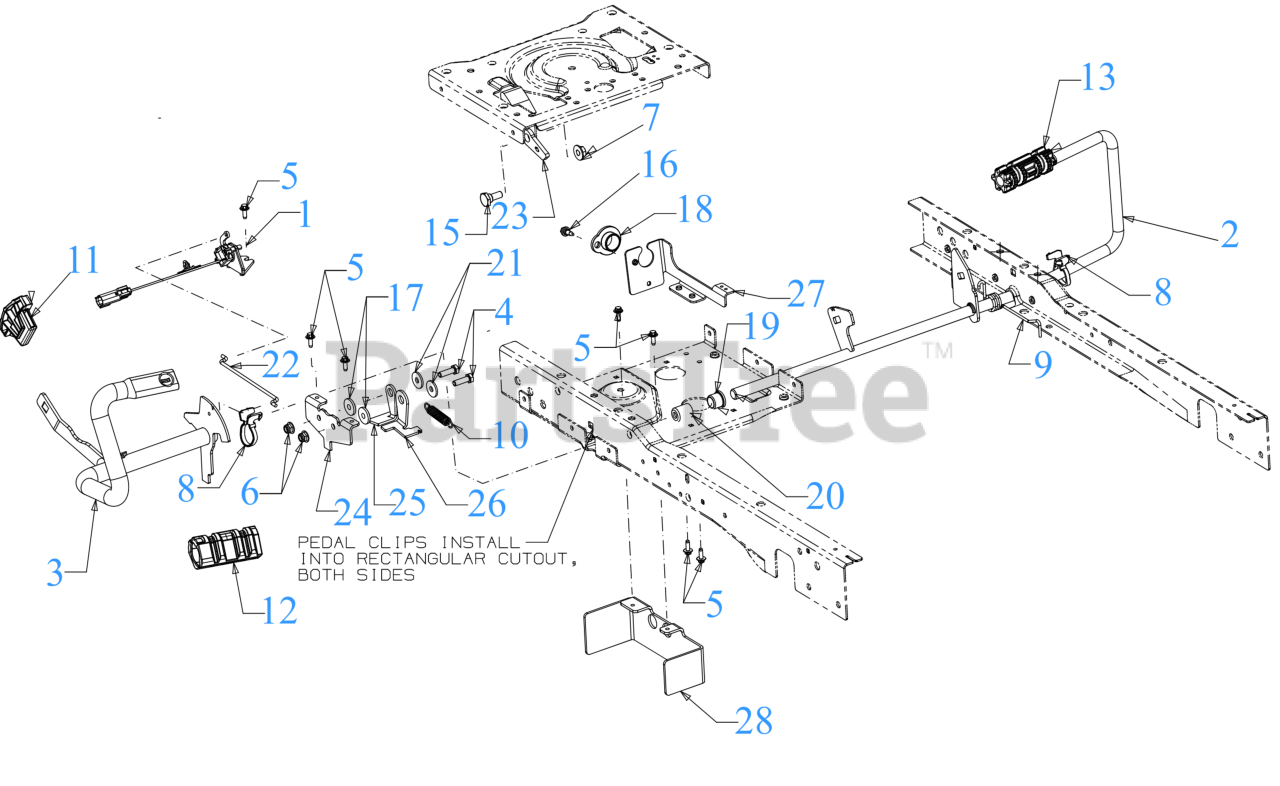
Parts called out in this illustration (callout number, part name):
1	THROTTLE SENSOR ASSEMLBLY
1	HARNESS CLIP
1	ROTARY SENSOR MAGNET
2	BRAKE PEDAL ASSEMBLY
3	FWD/REV PEDAL ASSEMBLY
4	SCREW 5/16-18 x 1.0 GR5
5	SCREW M6-1 x .625
6	FLANGE LOCK NUT 5/16-18
7	FLANGE LOCK NUT
9	TORSION SPRING .725
10	SPRING-EXT .51"DIA x 2.85"LG
11	REVERSE PEDAL PAD
12	FORWARD PEDAL PAD
13	BRAKE PEDAL PAD
15	SHOULDER SCREW
16	SHOULDER SCREW
17	SHOULDER SPACER (.315" x .50" x.14")
18	FLANGE BEARING
19	FLANGE BEARING .63X.84X.71
20	PLASTIC SLEEVE BEARING
21	THRUST BEARING (.323" x .985" x .1")
22	SWITCH ROD
23	CRUISE LATCH
24	NEUTRAL RETURN BRACKET
25	FORWARD RETURN BRACKET
26	REVERSE RETURN BRACKET
27	BRAKE SWITCH BRACKET
28	RETURN COVER PLATE
